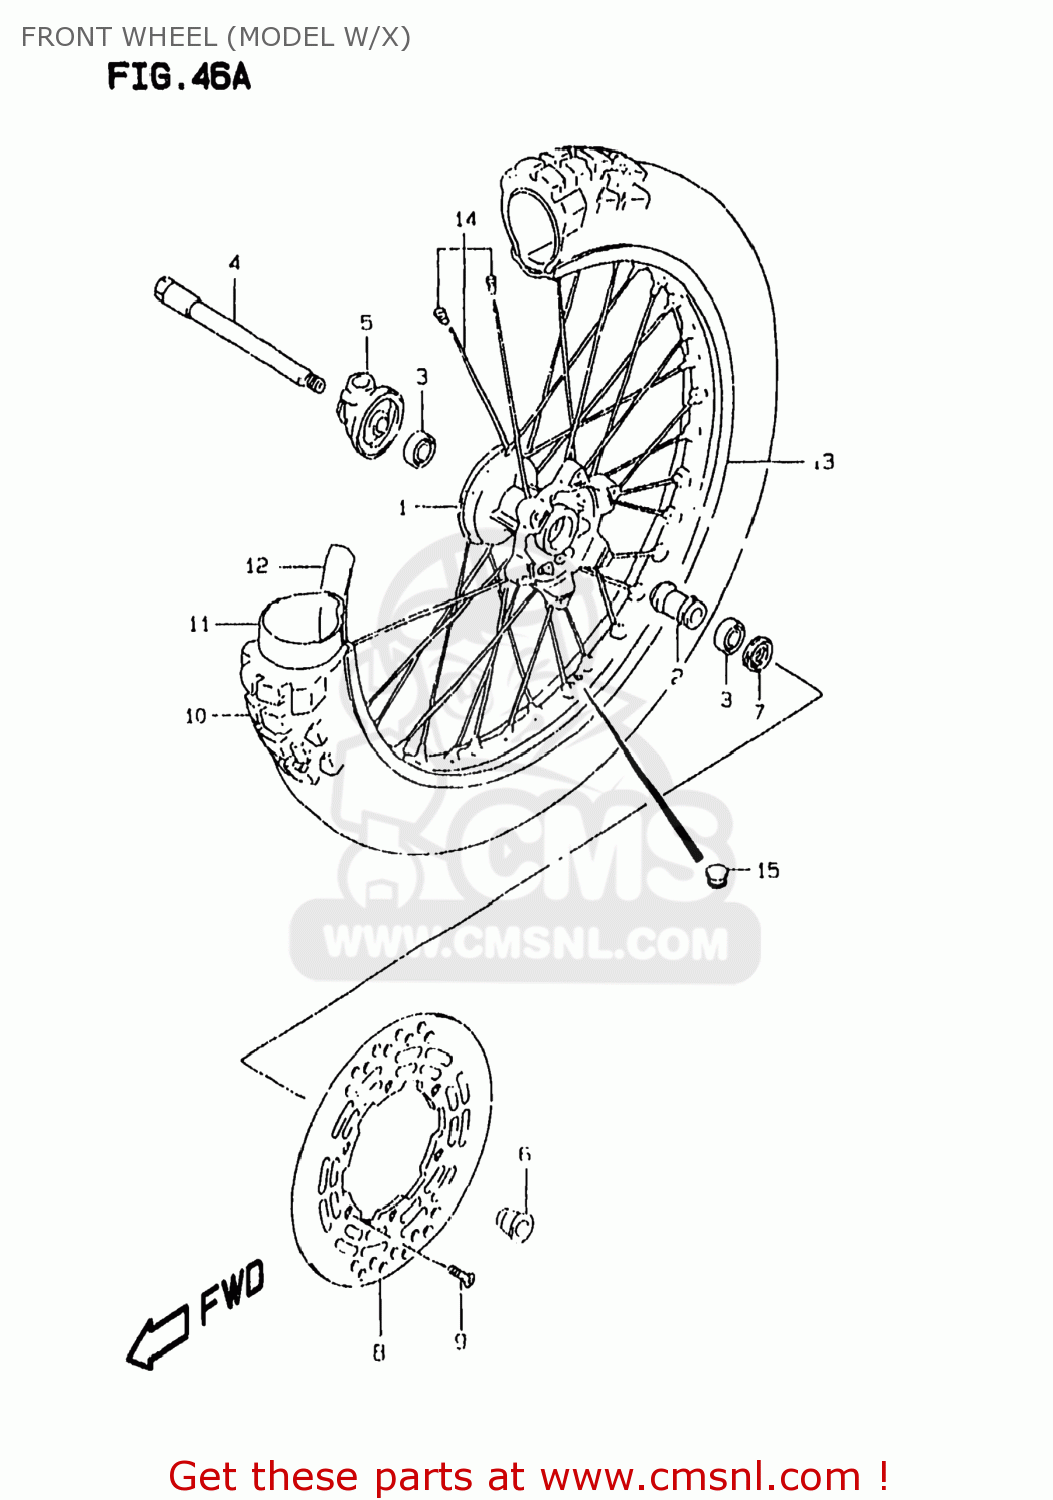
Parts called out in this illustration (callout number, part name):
1	HUB,FR WHEEL
2	SPACER,FR HUB BEARING
3	BEARING
4	AXLE,FR
5	BOX ASSY,SPEEDOMETER GEAR
6	SPACER,FR AXLE,L
7	SEAL,OIL(23X35X6)
8	DISC,FR BRAKE,L
9	SCREW
10	TIRE,FR(80/100 21)
11	TUBE
12	PROTECTOR,WHEEL INNER
13	RIM,FR WHEEL(1.60X21)
14	SPOKE SET,FR WHEEL
15	CAP(OD:12)
